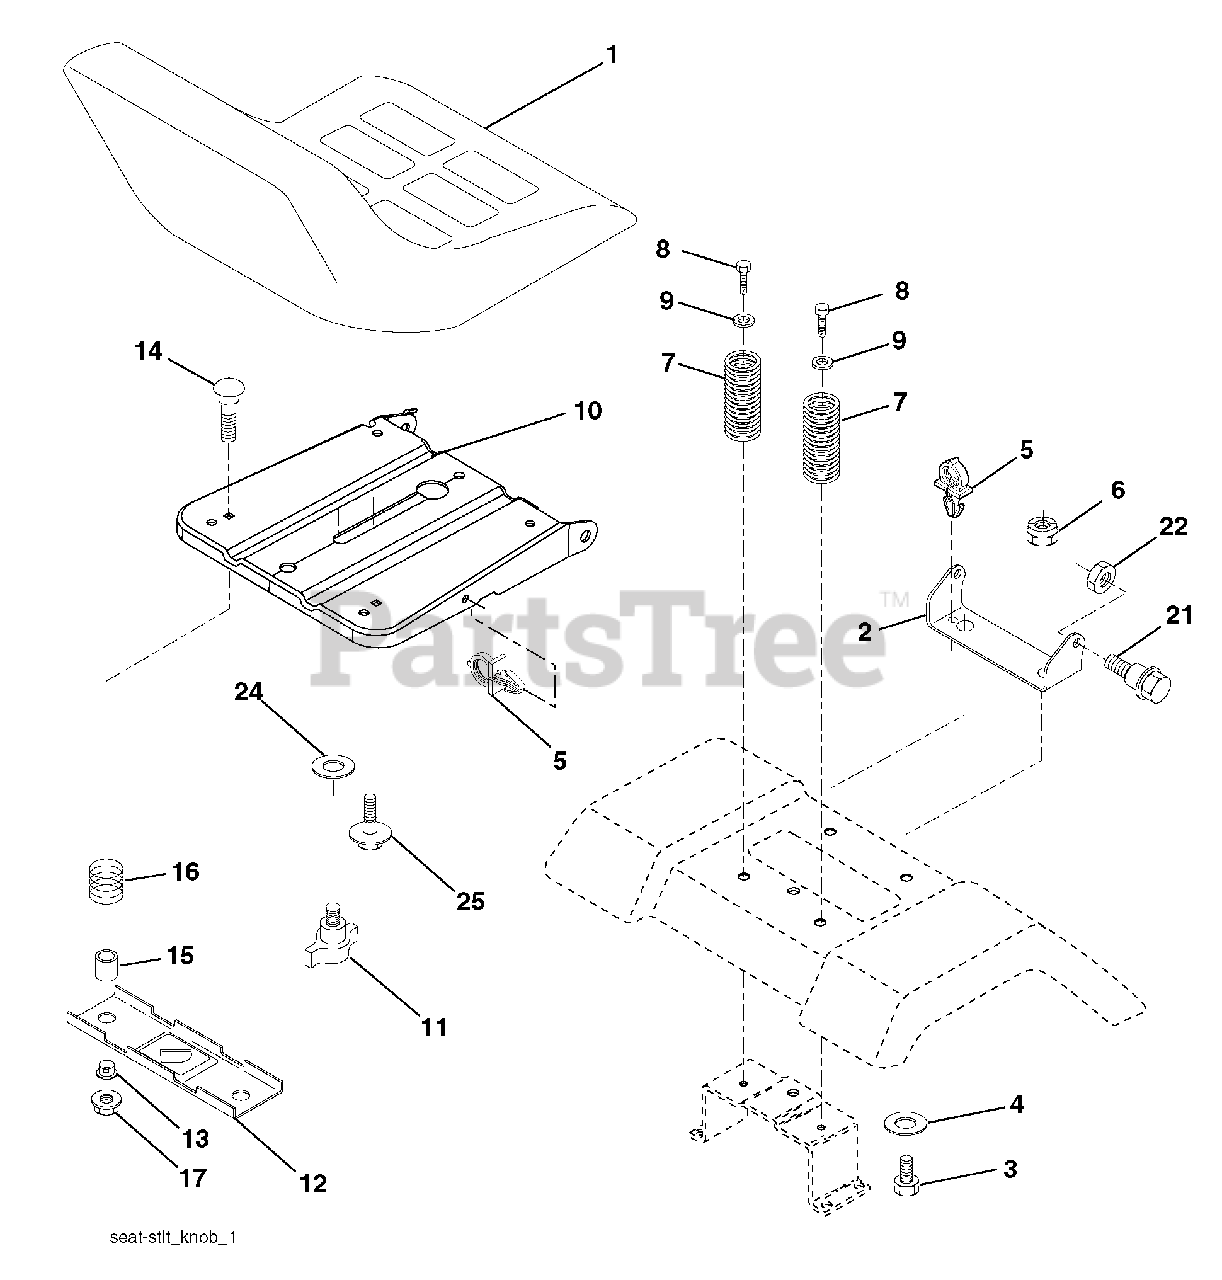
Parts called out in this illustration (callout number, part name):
1	Seat
2	Bracket Seat Pivot
3	Bolt Hex 3/8 - 16 x 1
4	Washer 13/32 x 1 x10 Ga.
5	Clip Push-In Hinged
6	Nut Lock Hex w/Ins 3/8 - 16
7	Spring Seat Cprsn 2 250 Blk Zi
8	Screw 3/8-16 x 1.5
9	Washer 13/32 x 1 x 14 Ga.
10	Pan Pnt Seat
11	Knob Seat
12	Bracket Pnt Mounting Switch
13	Bushing Snap Blk Nyl
14	Bolt Rdhd Sht Nk 1/4 - 20 x 1 -1/2
15	Spacer Split .28 x .96
16	Spring Cprsn
17	Nut Lock 1/4 Lge Flg
21	Bolt Shoulder 5/16-18 unc-2A
22	Nut Lock Hex w/Ins 5/16 - 18
24	Washer 17/32 x 1-3/16 x 12 Ga.
25	Bolt Shoulder 5/16-18 x .62
